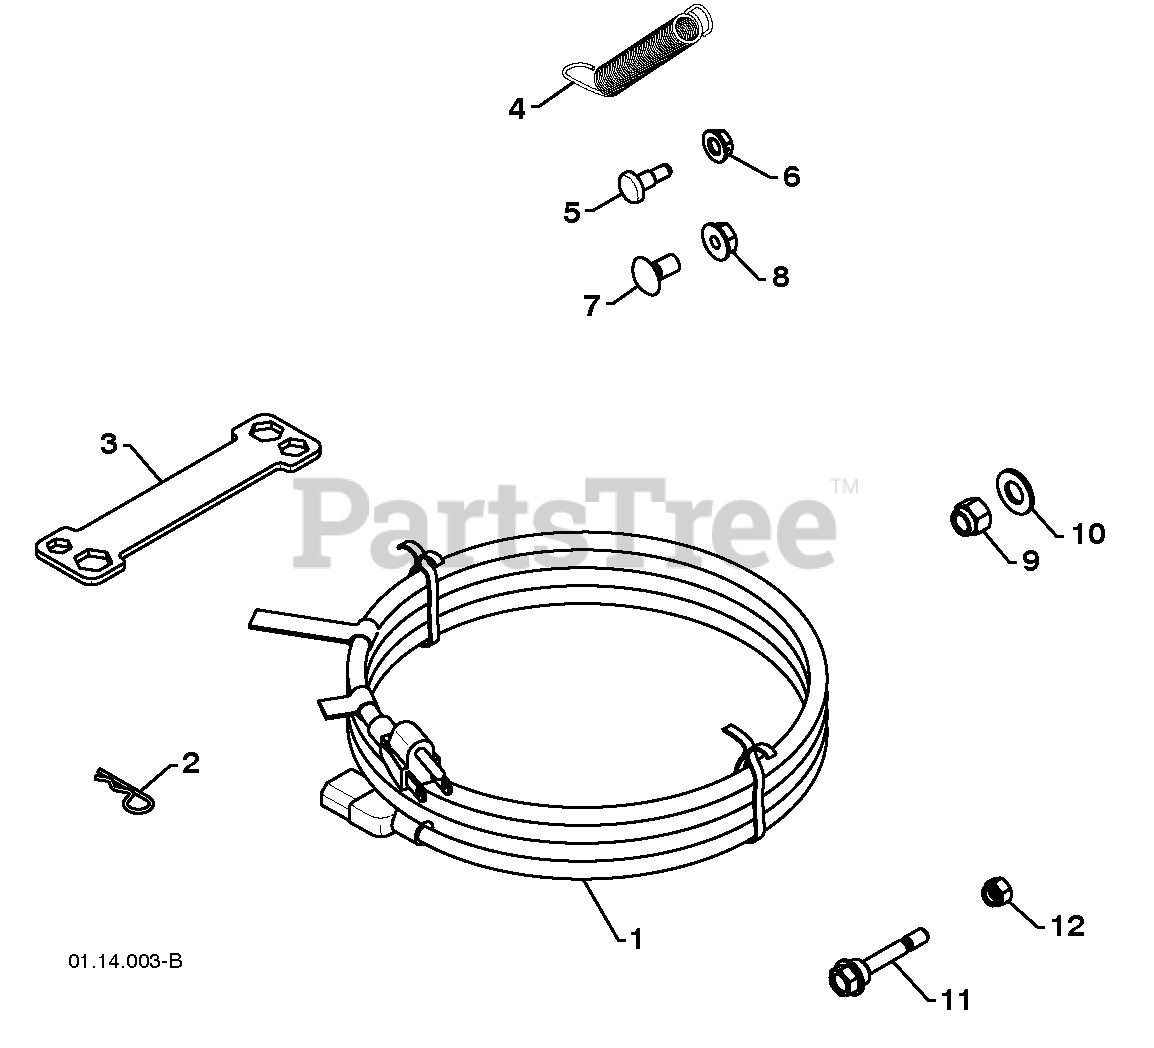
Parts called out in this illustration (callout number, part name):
1	POWER CORD
2	RETAINER PIN
3	WRENCH
4	REMOTE SPRING
5	SHOULDER BOLT 1/4-20
6	LOCKNUT 1/4-20
7	CARRIAGE BOLT 5/16-18 X 5/8
8	LOCKNUT 5/16-18
9	LOCKNUT 3/8-16
10	WASHER 3/8
11	SHEAR BOLT 1/4-20 X 1-13/16
12	LOCKNUT 1/4-20
